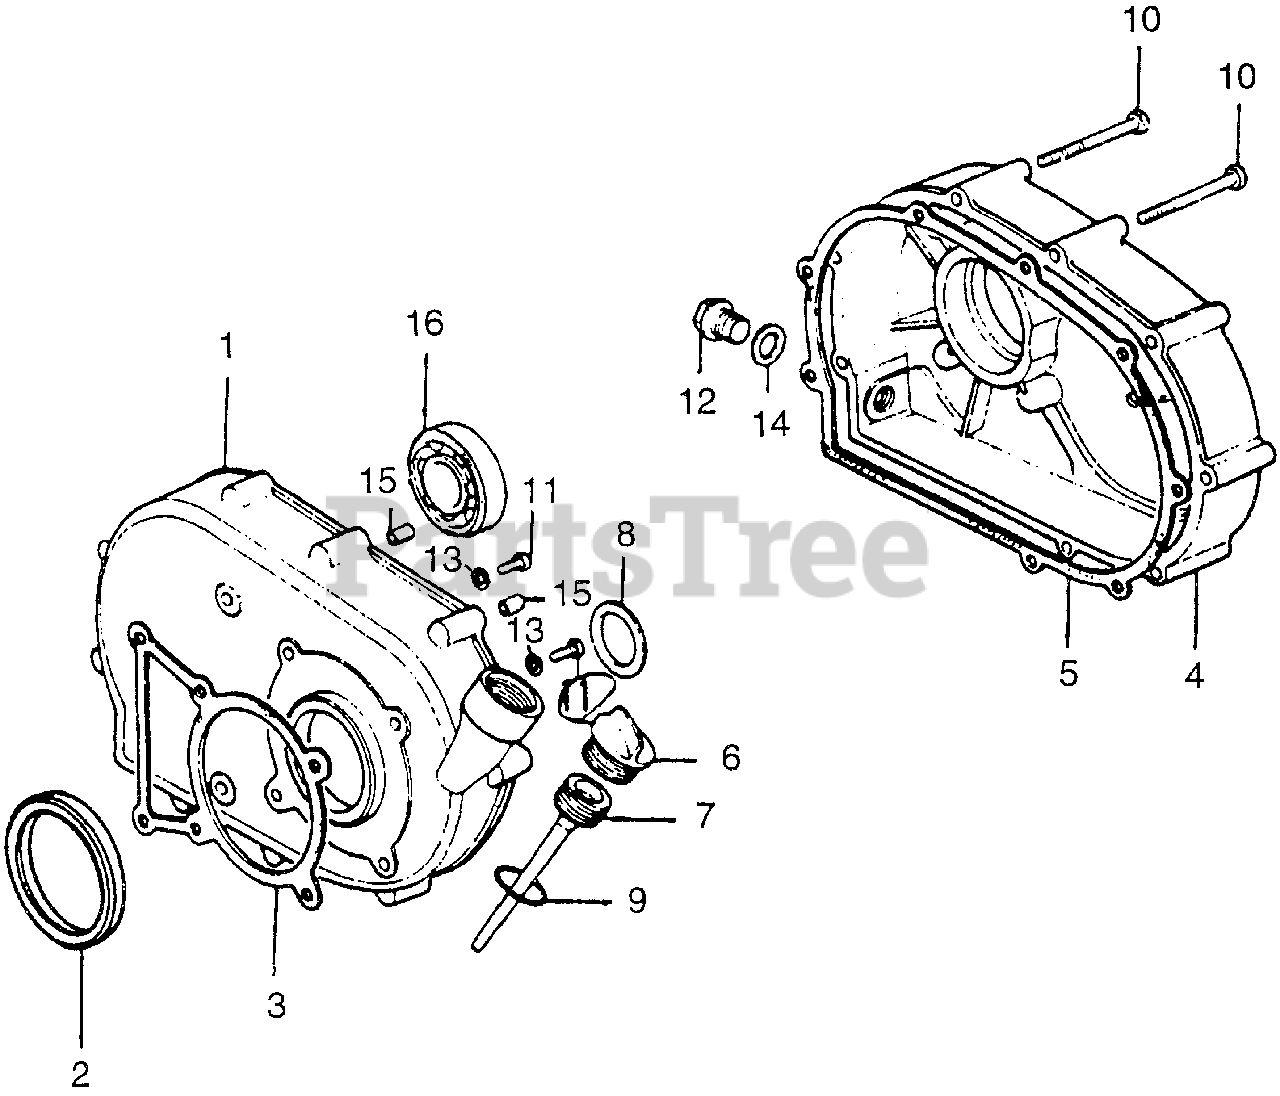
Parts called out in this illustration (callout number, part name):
1	CASE, REDUCTION
2	ADAPTER, RING
3	GASKET, REDUCTION CASE (NOT AVAILABLE)
4	COVER, REDUCTION
5	GASKET, REDUCTION
6	CAP, REDUCTION OIL (GRAY)
6	CAP, REDUCTION OIL
7	DIPSTICK, OIL (NOT AVAILABLE)
8	WASHER (22MM) (NOT AVAILABLE)
9	O-RING (26X2.7)
10	BOLT, HEX. (6X56)
10	BOLT, HEX. (6X56) (NOT AVAILABLE)
11	BOLT, HEX. (8X25)
12	BOLT, DRAIN PLUG (12MM)
13	WASHER, PLAIN (8MM)
14	WASHER, DRAIN PLUG (12MM)
15	PIN, DOWEL (8X14)
16	BEARING, RADIAL BALL (6206)
